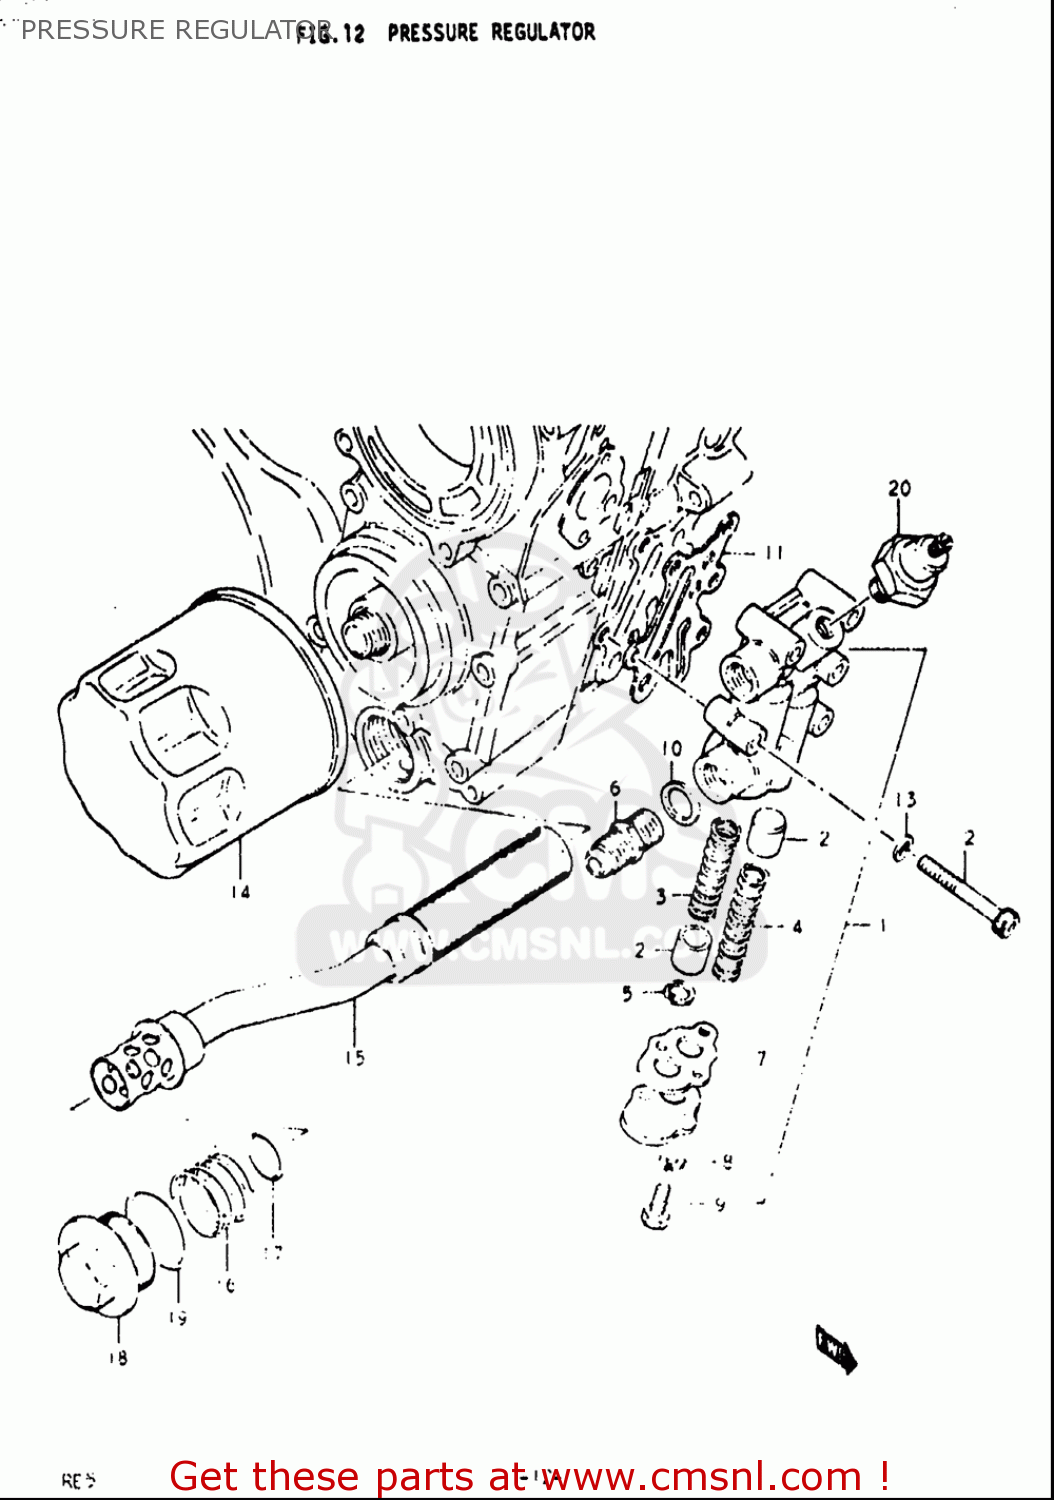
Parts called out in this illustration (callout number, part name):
8	WASHER,LOCK
9	BOLT
13	WASHER
14	FILTER ASSY,ENGINE OIL
17	O RING(D:2.4,ID:21.8)
19	O RING(D:2.2,ID:32)
20	SWITCH ASSY,OIL PRESSURE
